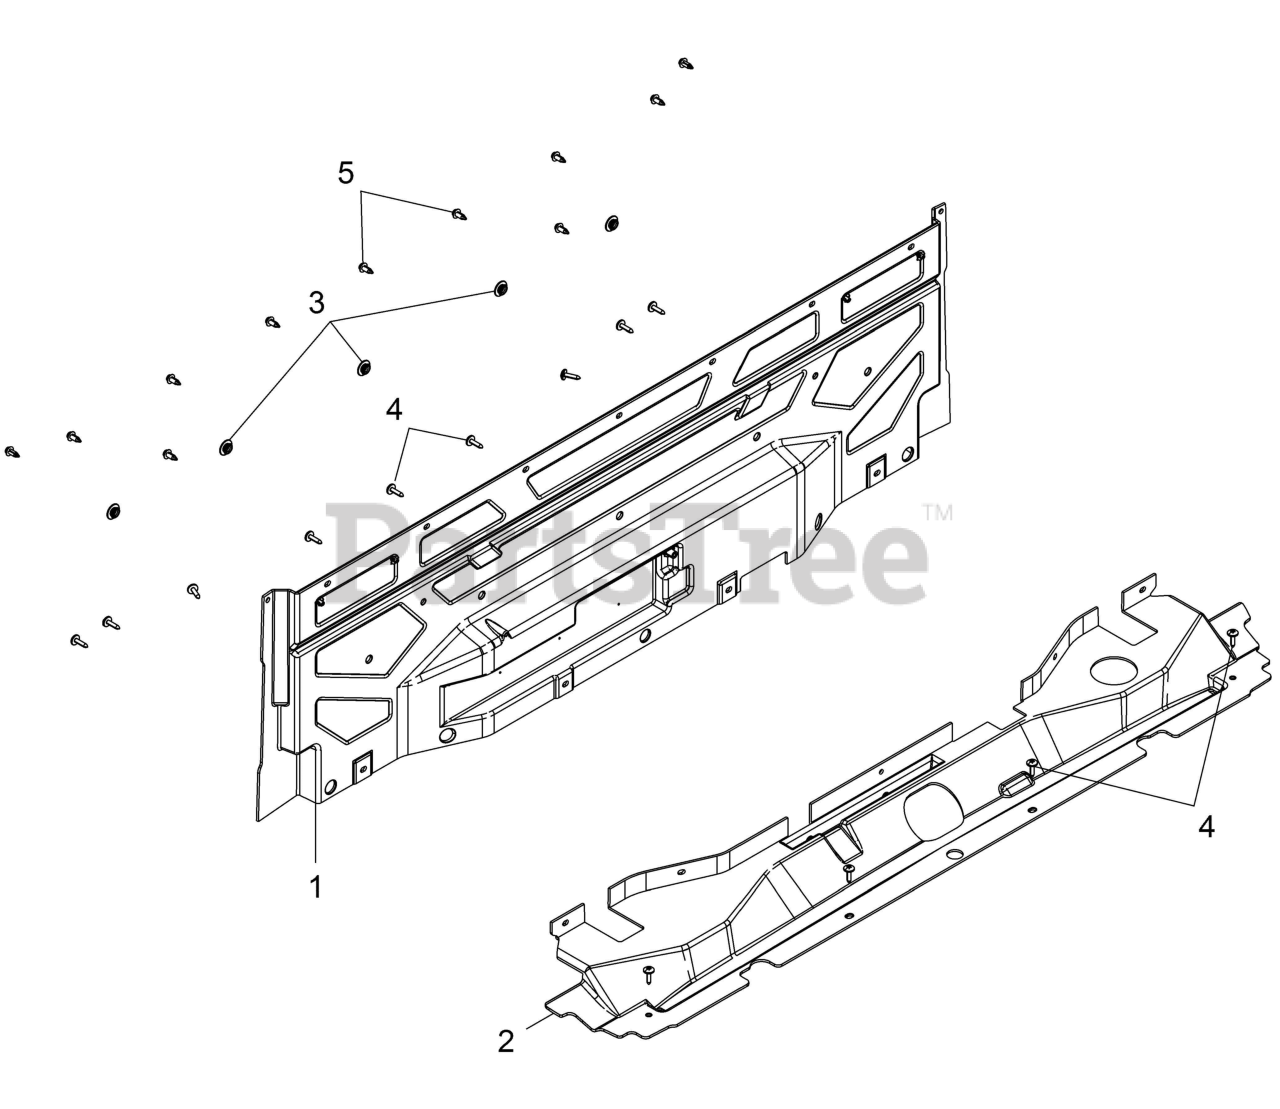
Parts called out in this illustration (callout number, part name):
1	PANEL, CLOSEOFF, REAR, BLK
2	PANEL-CLOSEOFF,LOWER,BLK
3	PLUG-COMPARTMENT
4	SCR-TXTH-M6X1.0X25 RIE
5	RIVET-TUFLOK,.315-.325X.787 (5
